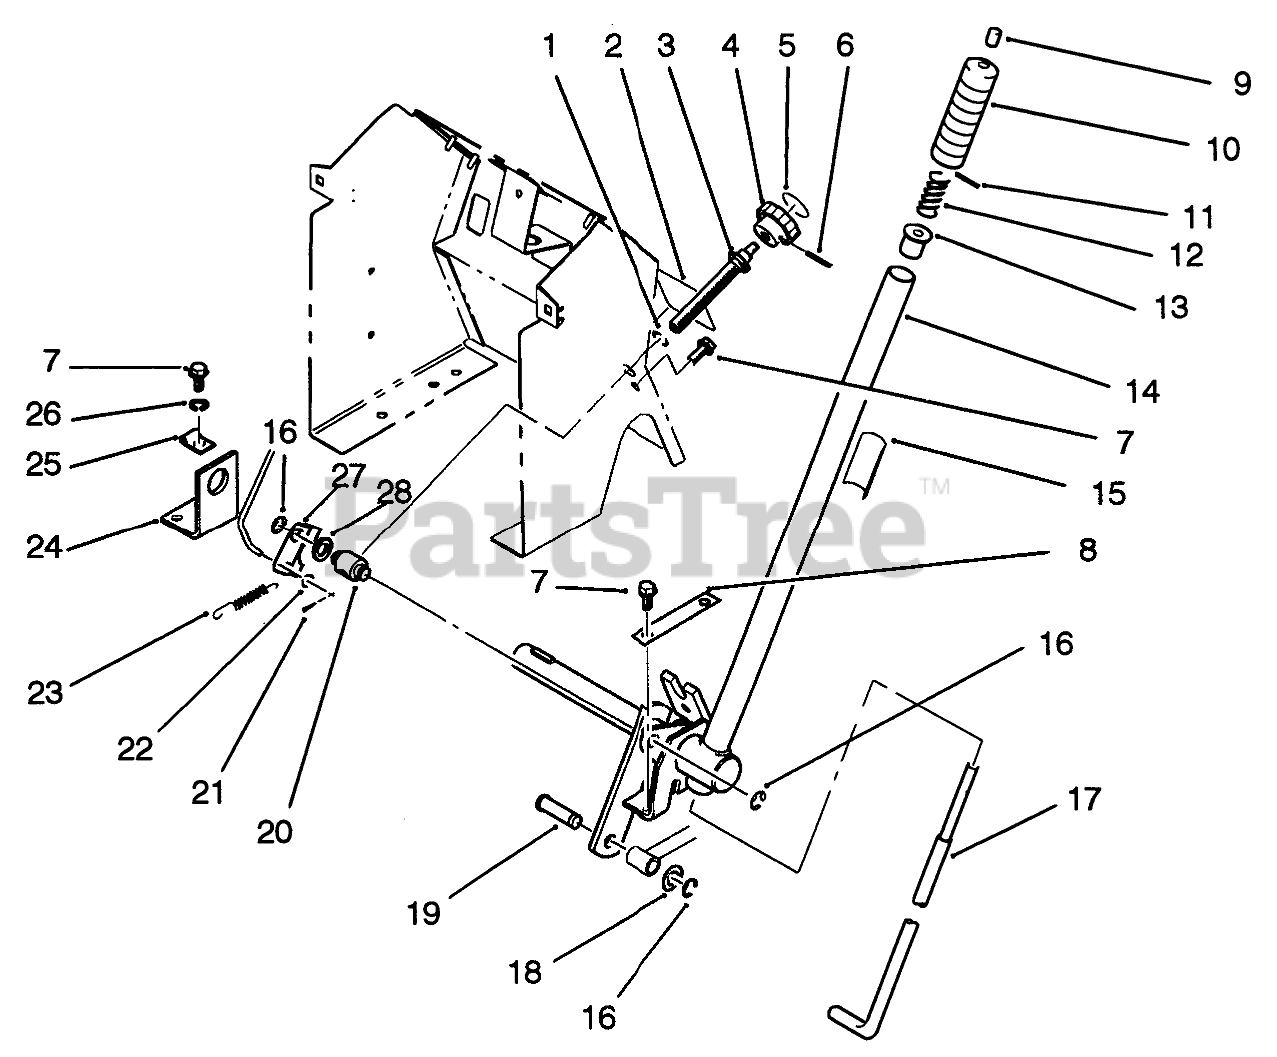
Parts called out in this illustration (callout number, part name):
1	Washer
2	DECAL-MWR ADJUST
3	ROD B
5	DECAL-HEIGHT KNOB
6	PIN-SPIROL
7	Screw
8	Plate
9	CAP-ROD, PLUNGER
10	HANDGRIP
11	PIN-SPIROL
12	SPRING-COMPRESSION
13	RETAINER-SPRING
14	Handle
15	DECAL-LIFT
16	RING-RETAINING, EXTERNAL
17	ROD-LATCH LIFT
18	WASHER-FLAT
20	TRUNNION
21	Cotter Pin
22	WASHER-FLAT
23	SPRING-EXTENSION
24	BRACKET B
25	THROTTLE CONTROL CLP
26	Washer-Lock
27	PLATE B
28	Washer
